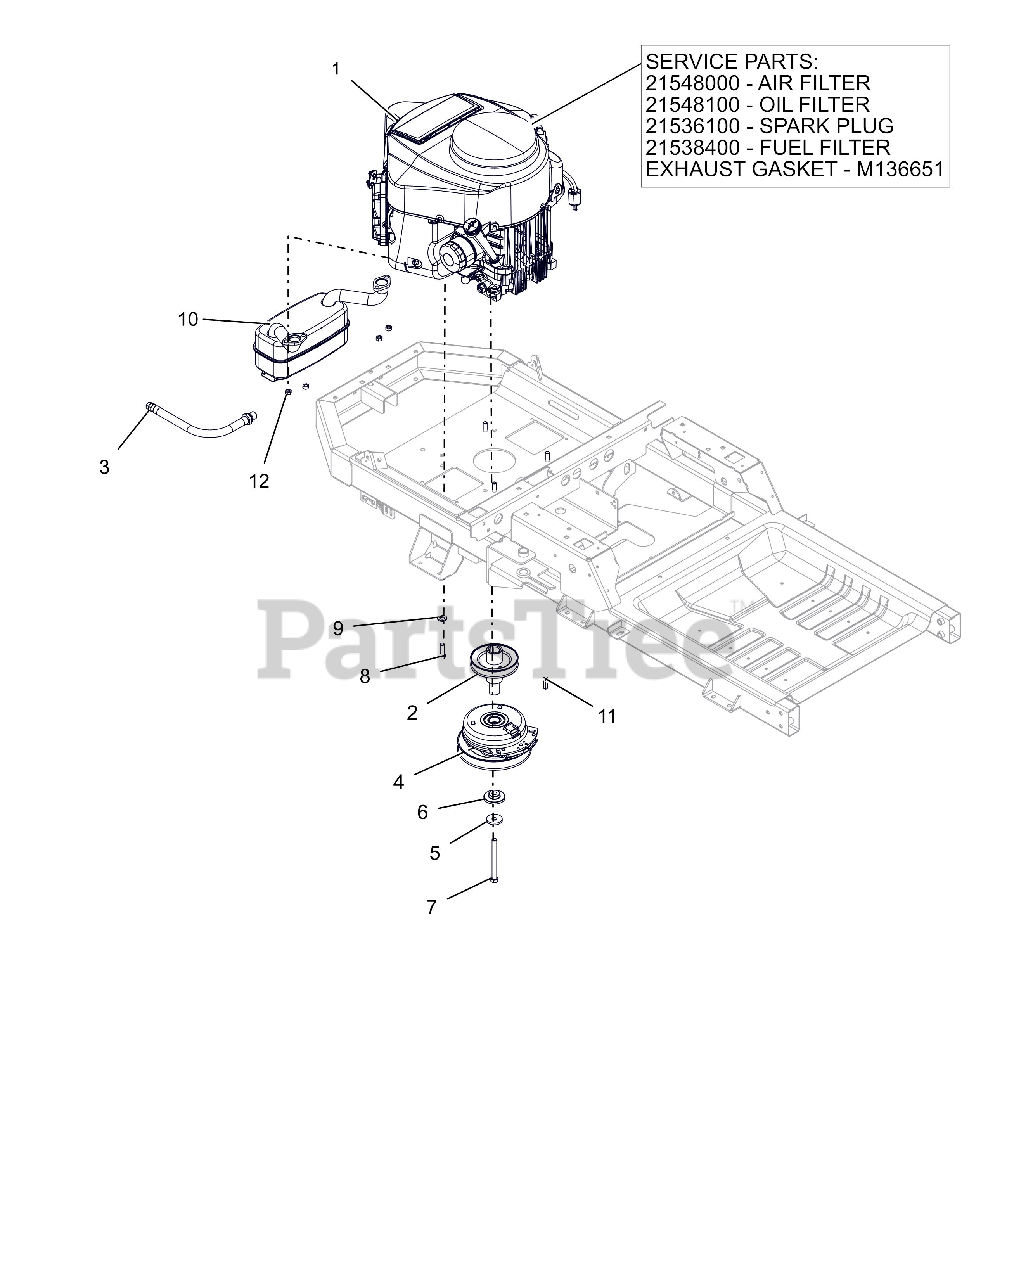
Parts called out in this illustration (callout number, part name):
1	ENGINE, KAWASAKI FR651V 22HP
1	AIR FILTER, KAWASAKI FR
1	OIL FILTER, KAWASAKI FR
1	PLUG, SPARK
1	FUEL FILTER - KAWASAKI
1	GASKET, MUFFLER #
2	WLDMT, DRIVE SHEAVE-X
3	HOSE, OIL DRAIN
4	CLUTCH,105FTLB MONOPOLE 6.83"
5	WASHER, 7/16" SPRING DISK
6	BSHG-FLG .469X1.06X.574X2.0
7	BLT-HEX.438-20X4.5GR8YZ NYTORQ
8	BLT-HEX.38-16X1.25 G5YZ NYTORQ
9	WASHER, 3/8" SPRING DISC
10	MUFFLER - KAWASAKI
11	KEY-SQ .25 X 1.25 X .25 SAE
12	NUT-LK-TOP M8-1.25 YWZC
